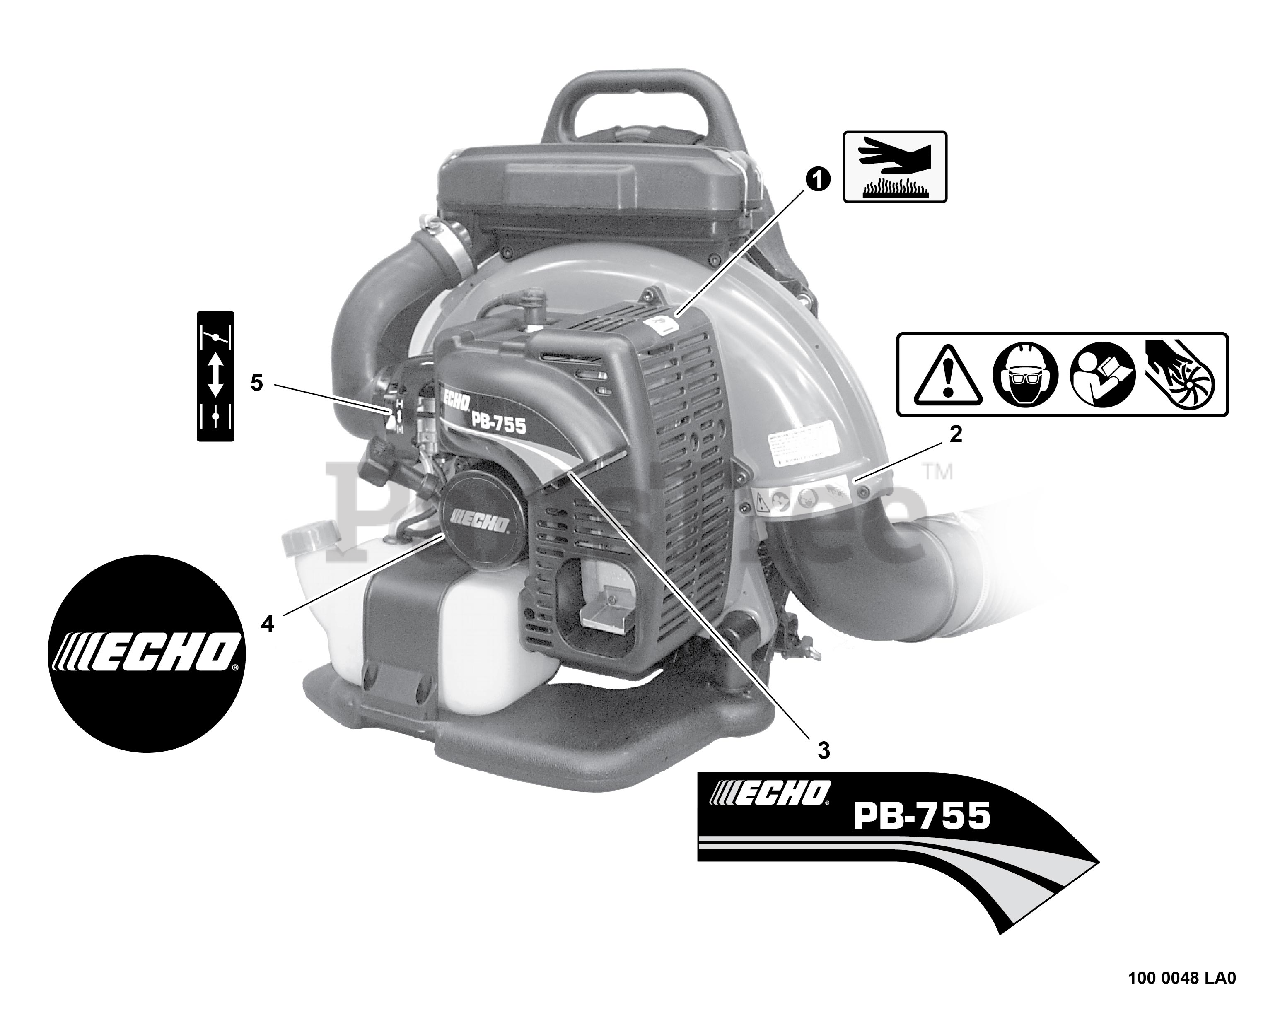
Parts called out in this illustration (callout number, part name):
1	LABEL - HOT SURFACE
2	LABEL - CAUTION
3	LABEL - MODEL PB-755
4	LABEL - ECHO
5	LABEL - CHOKE
